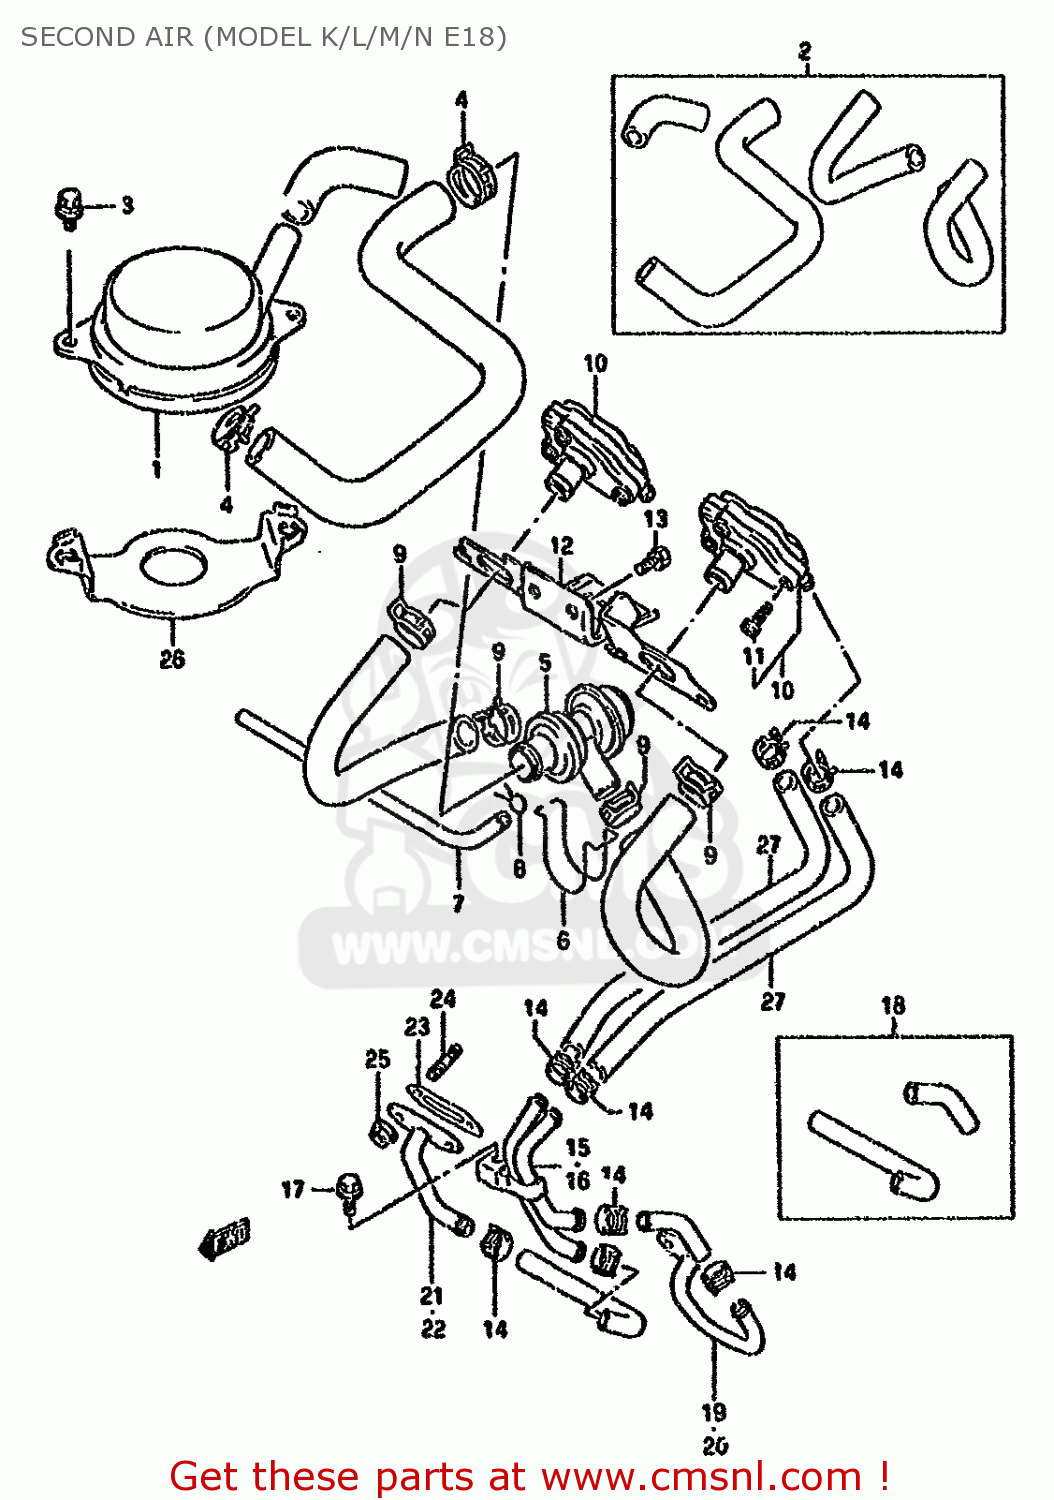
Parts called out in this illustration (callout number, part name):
1	CLEANER ASSEMBLY,SECOND AIR
2	HOSE SET,SECOND AIR NO.2
3	BOLT
4	CLIP
5	VALVE ASSY,AIR SWITCHING
6	CLAMP,SWITCHING VALVE
7	HOSE
8	CLAMP
9	CLIP
10	VALVE ASSY,2ND AIR REED
11	BOLT
12	(CA) B/K REED VALVE
13	BOLT
14	CLIP
15	PIPE,SECOND AIR,RIGHT
16	PIPE,SECOND AIR,LEFT
17	BOLT 6X12
18	HOSE SET,SECOND AIR NO.1
19	(CA) PIPE,SECOND AIR NO.1
20	(CA) PIPE,SECOND AIR NO.4
21	PIPE,2ND AIR NO.2
22	PIPE,2ND AIR NO.3
23	GASKET,SECOND AIR PIPE (NAS)
24	STUD BOLT
25	NUT 6MM
26	HOLDER,SECOND AIR CLEANER
27	(CA) HOSE,SECOND AIR NO.1
